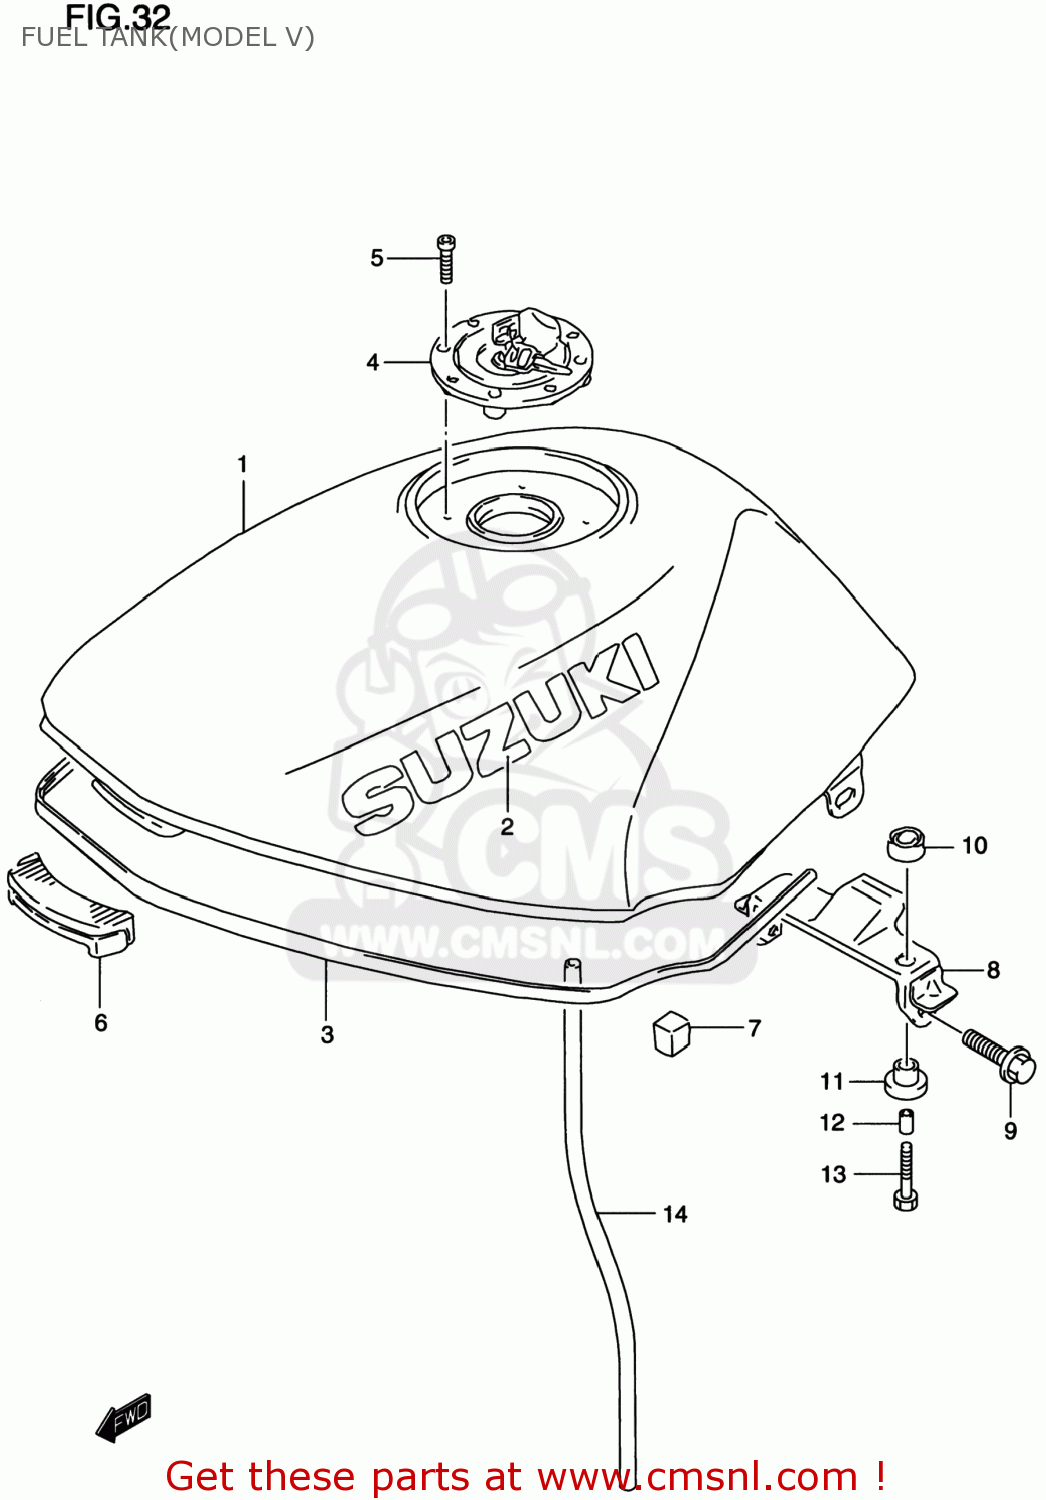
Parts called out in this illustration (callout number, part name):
1	TANK ASSEMBLY,FUEL
2	EMBLEM,FUEL TANK
3	MOLDING
4	CAP SET,FUEL
5	BOLT(5X20)
6	CUSHION,FUEL TANK FR
7	CUSHION,FUEL TANK SIDE
8	BRACKET COMP,FUEL TANK
9	BOLT
10	CUSHION
11	CUSHION
12	SPACER(6.5X9X18)
13	BOLT(6X30)
14	HOSE,WATER DRAIN
